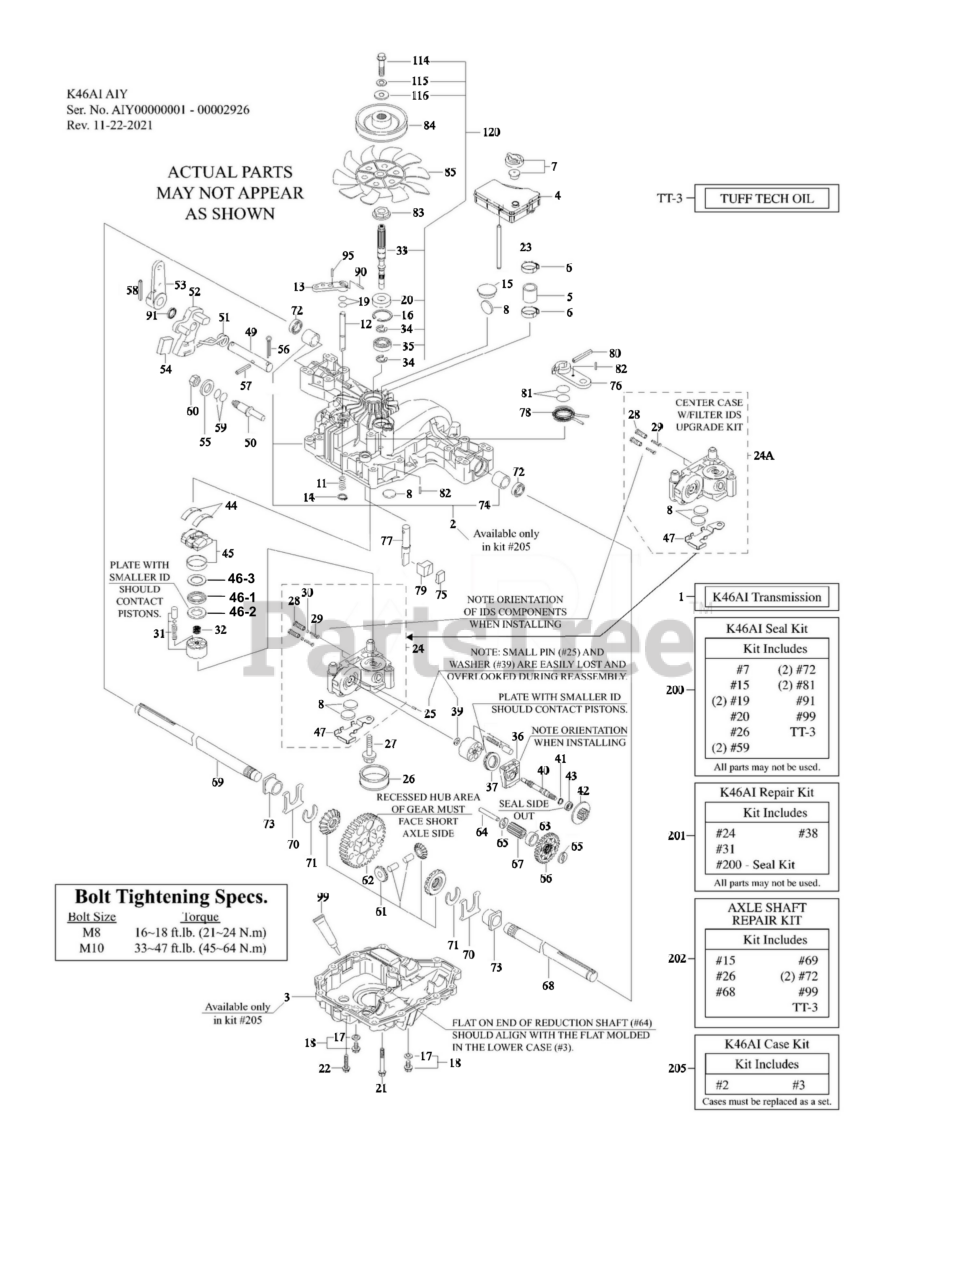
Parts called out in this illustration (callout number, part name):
1	TRANSMISSION
4	TANK, Fuel
6	CLAMP, Hose
12	BYPASS SHAFT
18	DRAIN BOLT KIT
23	TANK SUPPORT
26	FILTER, Oil
31	PUMP, Oil
36	MOTOR HOUSING
38	PUMP, Oil
40	MOTOR SHAFT
41	RING, Locking
44	THRUST, Metal
45	KIT, Input Shaft
47	MAGNET HOLDER
49	CONTROL SHAFT
50	FULCRUM
51	TORSION SPRING
52	CONTROL ARM A
56	COTTER PIN 1/8 INCH 3/4 INCH
58	ROLL PIN 6 * 40
61	KIT, Differential
64	REDUCTION SHAFT
68	SHAFT, Axle
69	SHAFT, Axle
70	THRUST WASHER
72	SEAL, 19 * 32 * 8
73	BUSHING, 19 * 25
75	BRAKE SHOE
76	BRAKE LEVER
77	BRAKE SHAFT
78	BRAKE RETURN SPRING
79	BRAKE ACTUATOR
85	FAN, White
91	OIL SEAL 16 * 22 * .03
99	SEALANT
115	LOCK WASHER
120	PUMP SHAFT/BEARING KIT
200	K46 & T40 SEAL KIT
201	BODY, Pump
202	AXLE REPAIR KIT
205	HOUSING KIT
